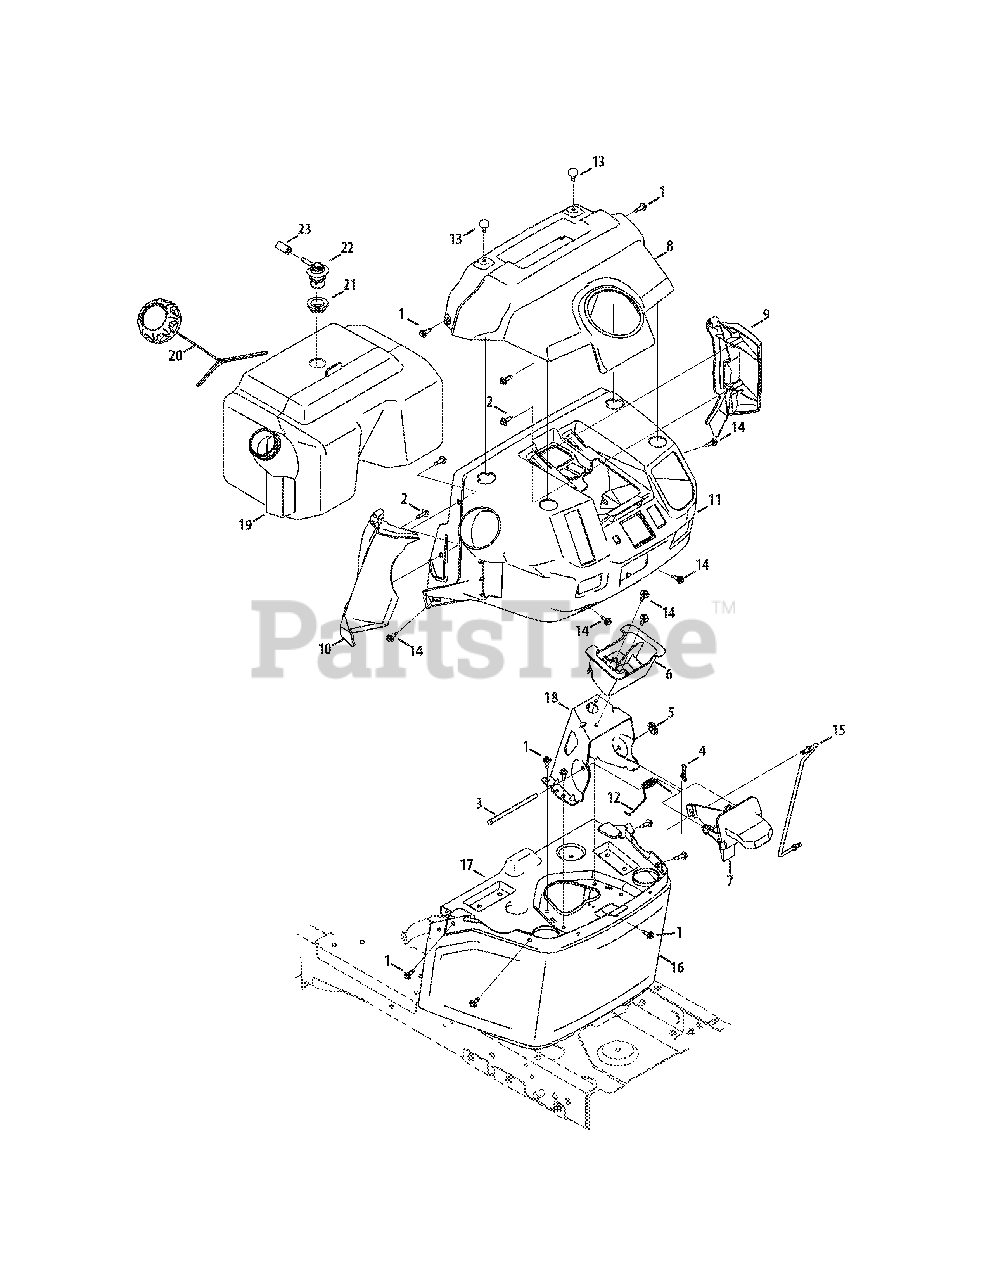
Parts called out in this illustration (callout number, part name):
1	Screw, M6-1 x .625
2	Screw, 1/4-10 x .75
3	Hinge Pin, .25 Dia x 4.50 LG
4	Pin, Cotter, Bow-Tie 72
5	Push Nut, .25 dia.
6	Steering Shaft Bearing
7	Dash Lever
8	Dash Cap
9	Dash Cap, RH
10	Dash Cap, LH
11	Upper Dash
12	Torsion Spring, .330 ID
13	Bumper, .62 Dia x .3
14	Shoulder Screw, .368 x .115, M6-1
15	Control Rod
16	Lower Dash
17	Dash Plate
18	Steering Bearing Mounting Bracket
19	Tank, Fuel, 3 Gal.
20	Fuel Cap
21	Grommet, Rubber, 23.0 ID
22	Valve, Rollover Grommet
23	Hose, Vent
